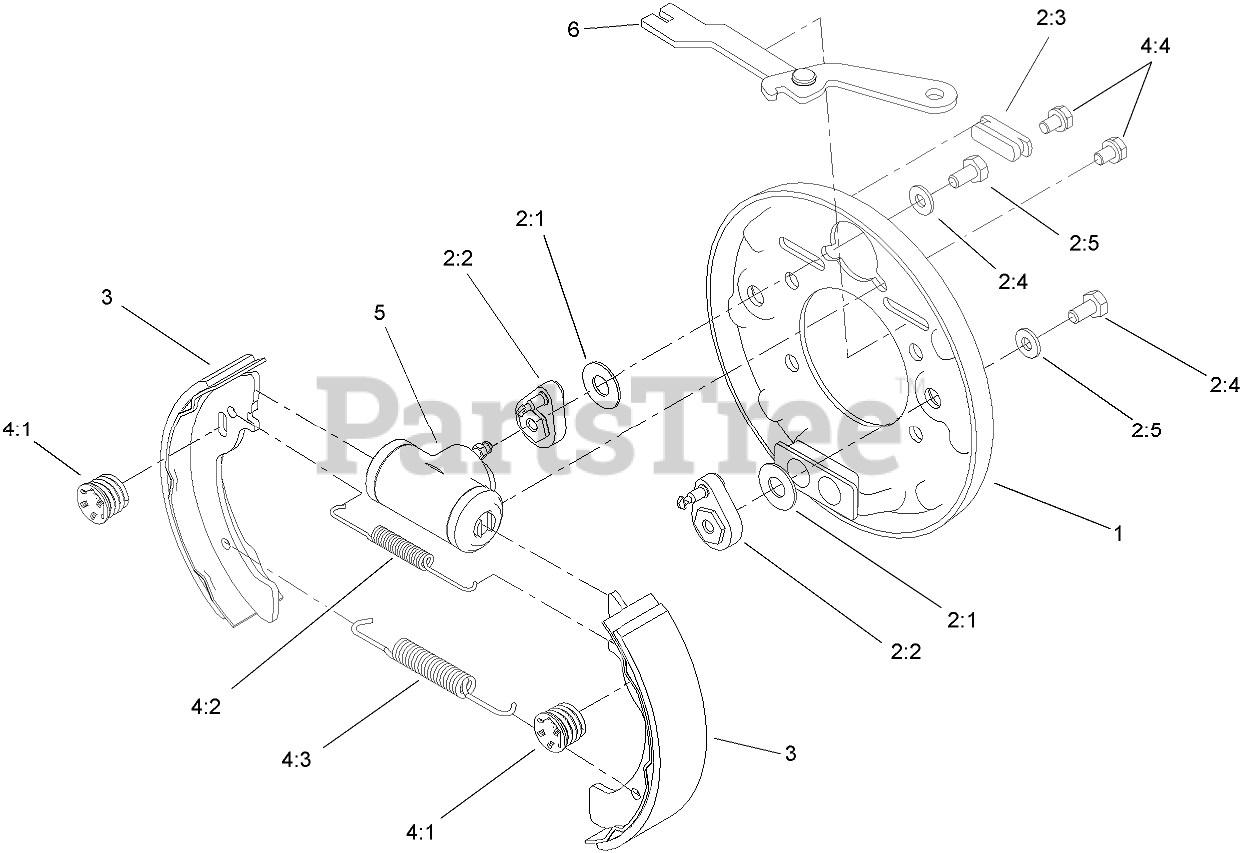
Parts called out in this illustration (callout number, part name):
1	BACKING PLATE ASM
2	ADJUSTER KIT
2:1	WASHER-BELLVILLE
2:2	ADJUSTER LEVER ASM
2:3	COVER-DUST
2:4	Washer
2:5	Bolt
3	SHOE AND LINING KIT
4	HARDWARE KIT
4:1	SHOE HOLD DOWN SPRING ASM
4:2	SPRING-UPPER
4:3	SPRING-LOWER
4:4	BOLT AND WASHER
5	WHEEL CYLINDER ASM
6	LH PARK BRAKE LEVER ASM
